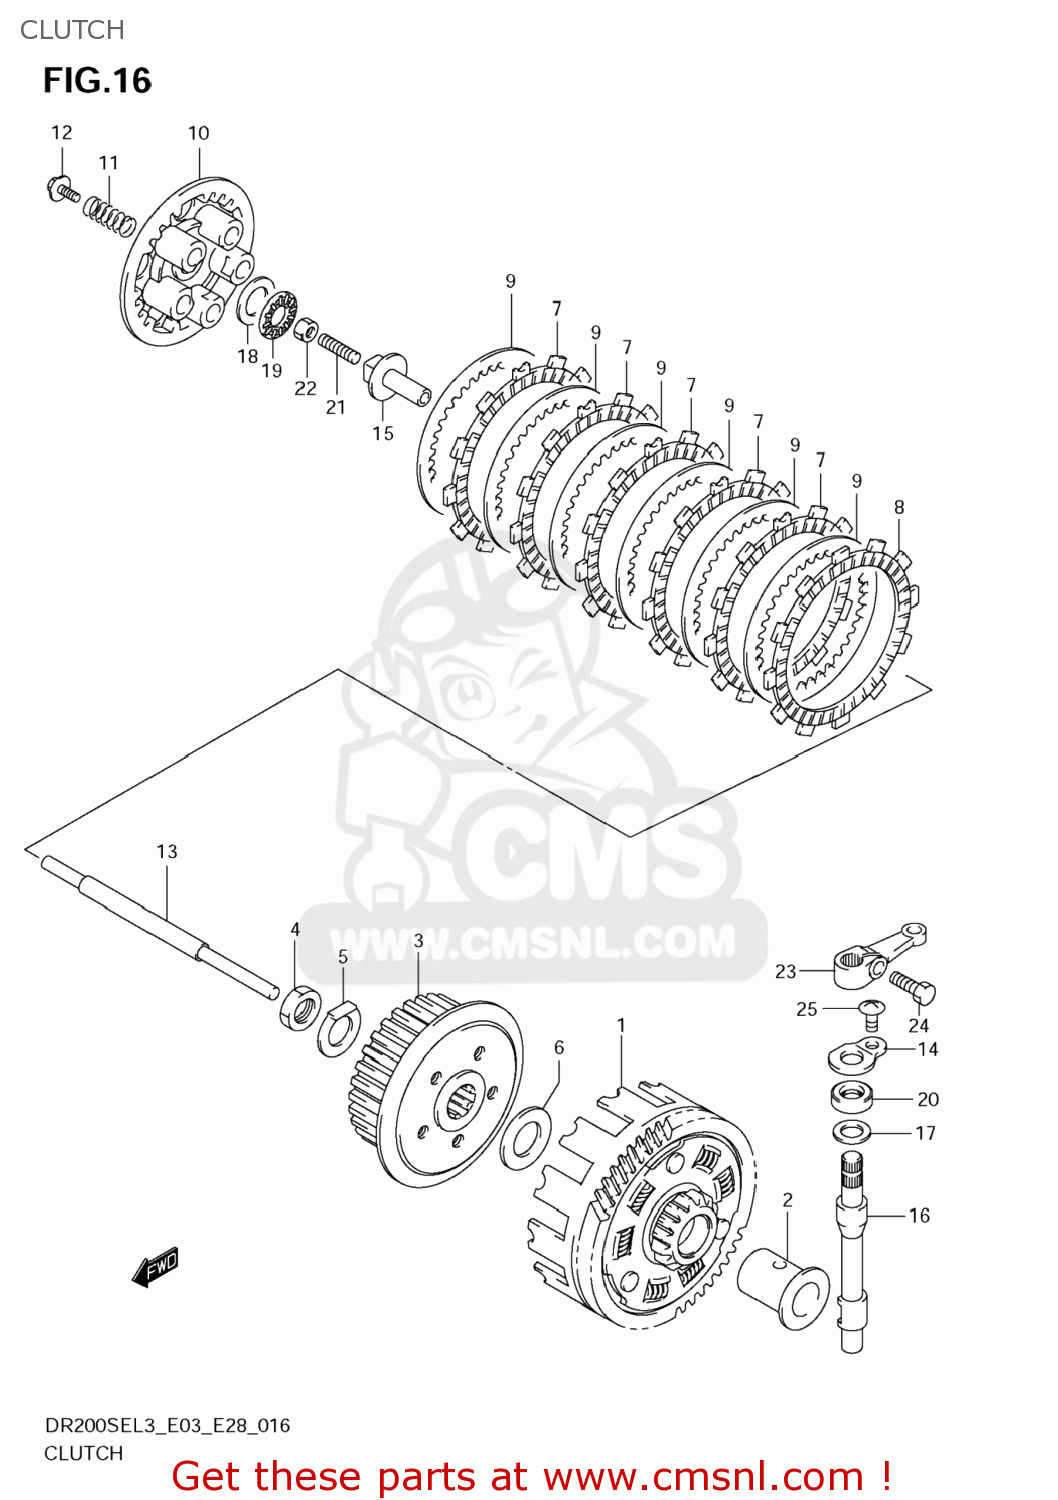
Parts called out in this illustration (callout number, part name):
1	GEAR ASSY,PRI DRIVEN
2	SPACER,PRIMARY DRIVEN GEAR
3	HUB,CLUTCH SLEEVE
4	NUT
5	WASHER
6	WASHER
7	PLATE,CLUTCH DRIVE (NAS)
8	PLATE,CLUTCH DRIVE(T:3.0) (NAS)
9	PLATE,DRIVEN(T:1.4)
10	DISC,CLUTCH PRESSURE
11	SPRING
12	BOLT(5X16)
13	ROD,CLUTCH PUSH
14	RETAINER,CL RLSE OIL SEAL
15	PIECE,CLUTCH PUSH
16	CAMSHAFT,CLUTCH RELEASE
17	SHIM(10X20X1)
18	WASHER(15.5X28X1)
19	BEARING(15X28X2)
20	SEAL,OIL(10X20X6)
21	SCREW(6X25)
22	NUT
23	ARM,CLUTCH RELEASE
24	BOLT
25	SCREW
